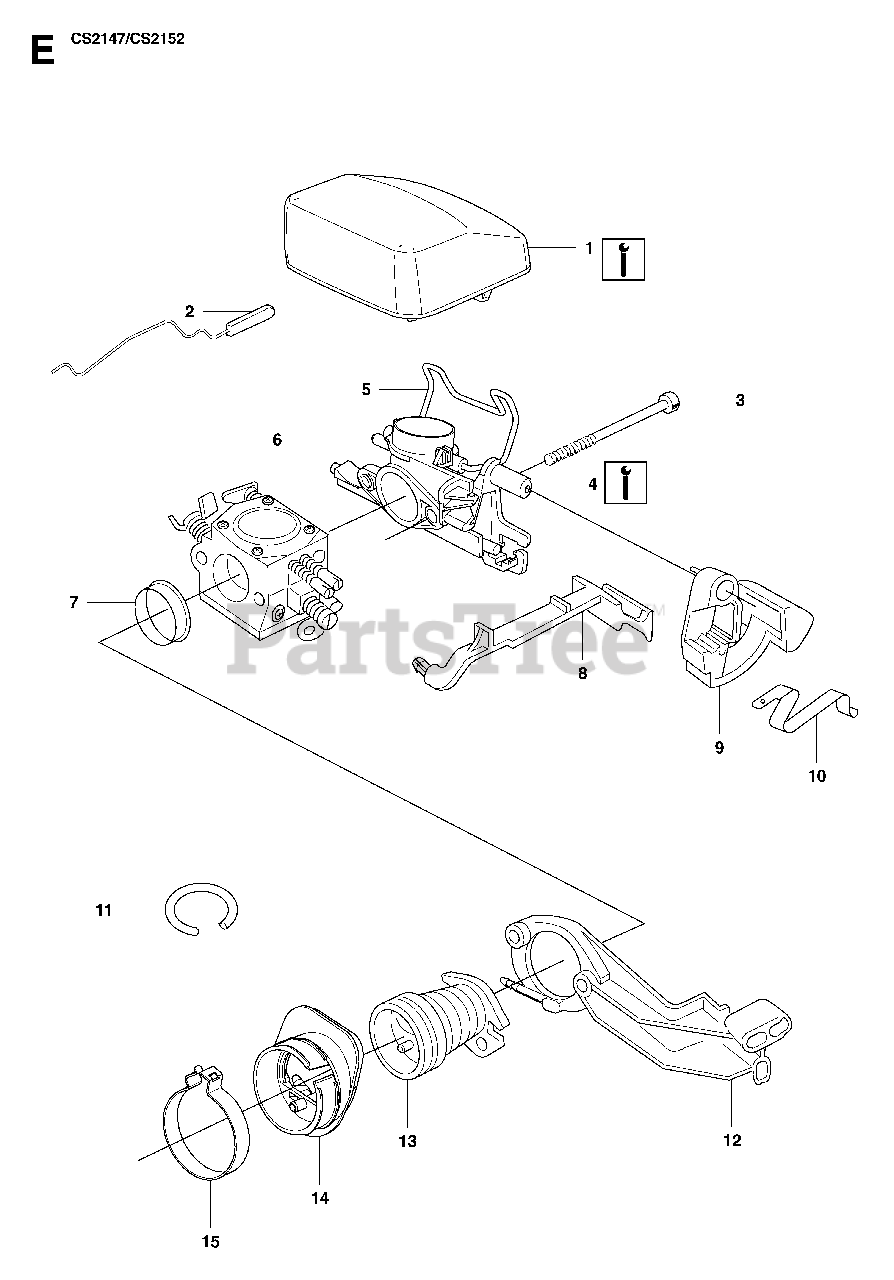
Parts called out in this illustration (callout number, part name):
1	AIR FILTER - NYLON (B)
1	AIR FILTER - NYLON (Y)
1	AIR FILTER - FELT
2	THROTTLE ROD
4	INTAKE BOOT
5	FILTER CLAMP
6	CARBURETOR C3-EL18
8	CHOKE CONTROL
11	HOSE, IMPULSE
13	BELLOWS
14	PARTITION
15	CLAMP, INTAKE
